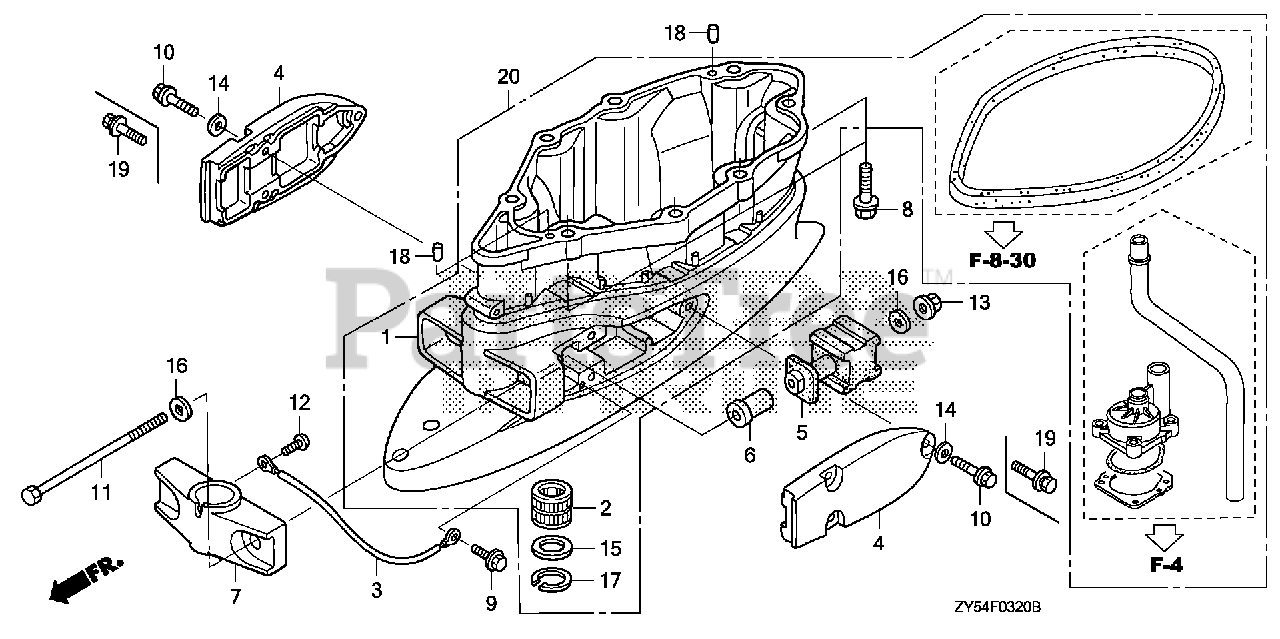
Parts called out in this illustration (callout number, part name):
1	CASE, EXTENSION *NH282MU* (L) (OYSTER SILVER METALLIC-U)
3	WIRE, LEAD (1.2X137MM)
4	HOUSING, MOUNTING (LOWER) *NH282MU* (OYSTER SILVER METALLIC-U)
5	RUBBER, MOUNT (LOWER)
6	COLLAR, MOUNTING (LOWER)
7	HOUSING, CENTER MOUNTING (LOWER) *NH282MU* (OYSTER SILVER METALLIC-U)
8	BOLT, FLANGE (10X40)
9	BOLT, FLANGE (6X12)
10	BOLT, HEX. (8X30)
11	BOLT, HEX. (12X225)
12	SCREW, PAN (6X8)
13	NUT, FLANGE (12MM)
14	WASHER, PLAIN (8MM)
16	WASHER, PLAIN (12MM)
18	PIN, DOWEL (6X10)
